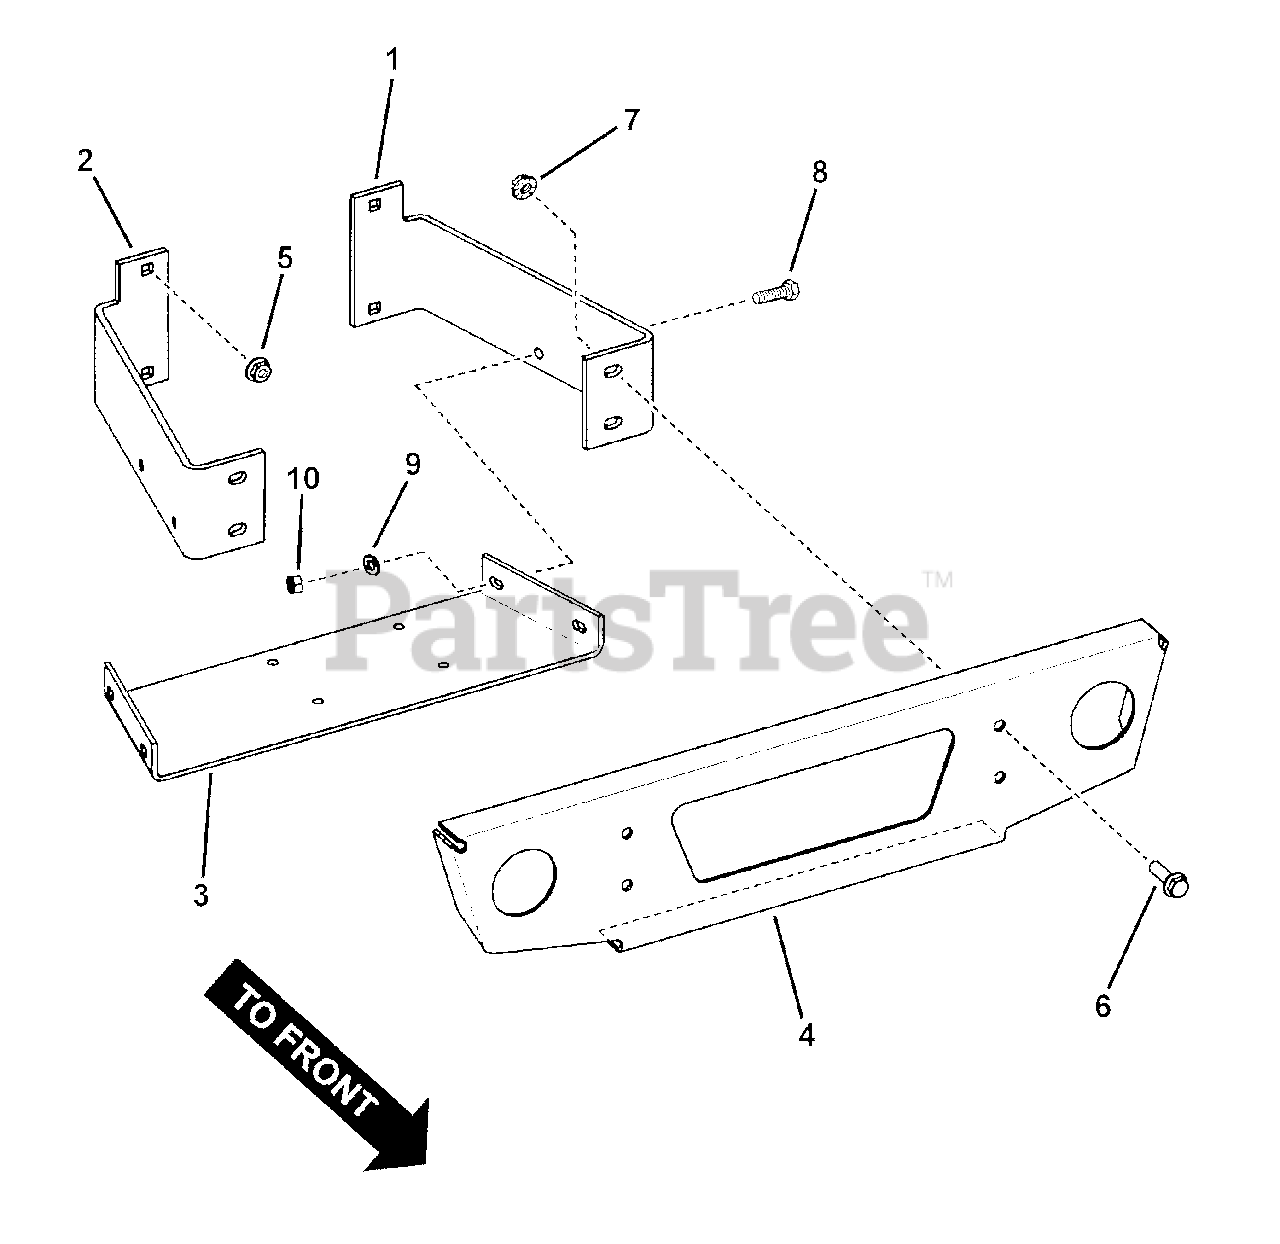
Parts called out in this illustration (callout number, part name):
1	BUMPER SUPPORT, Left
2	BUMPER SUPPORT, Right
3	PLATE, Winch Mounting
4	BUMPER
5	NUT, 3/8-16 Hex Nyloc
6	BOLT, 3/8-16 x 1" Hex Flange Lock, GR 5
7	NUT, 3/8-16 Hex Flange Lock
8	SCREW, 5/16-18 x 1" Hex Head Cap, GR 5
9	WASHER, .34 x .69 x .08 Flat
10	NUT, 5/16-18 Hex Nyloc
